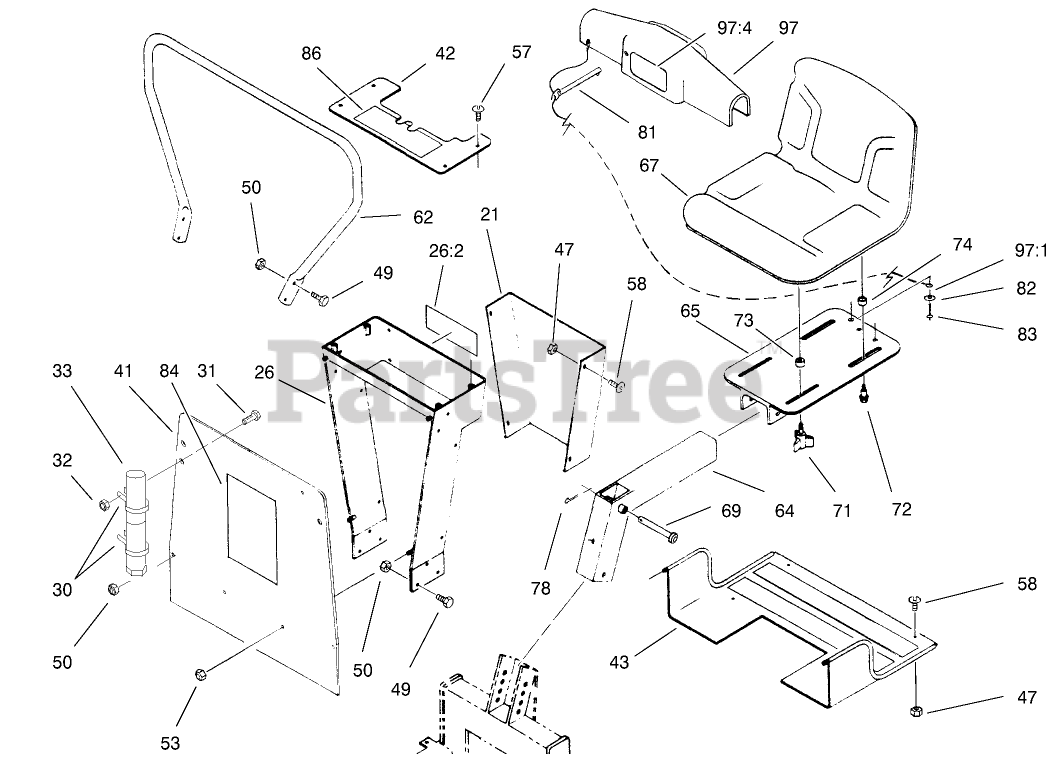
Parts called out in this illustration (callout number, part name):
21	GUARD-HOSE
26	VALVE MOUNT ASM
26:2	DECAL-WARNING
30	CLAMP-R
32	NUT-LOCK, NI
33	TUBE-MANUAL
41	PANEL-FRONT
42	COVER-VALVE
43	FOOT PLATE ASM
47	NUT-LOCK
49	SCREW-HH
50	NUT-LOCK, NI
53	NUT-LOCK, NI
57	SCREW
62	HANDLE-GUARD
64	SEAT MOUNT ASM
65	SEAT PLATE ASM
67	SEAT
69	PIN-CLEVIS
72	BOLT-SHOULDER
73	SPACER-NYLON
74	SPACER-NYLON
78	PIN-COTTER
81	PIN-COTTERLESS
82	Washer
83	RIVET-POP
84	DECAL-DINGO
86	DECAL-PANEL, CONTROL
97	CLIP ASM-BACKHOE
97:1	LANYARD
97:4	DECAL-CLIP
